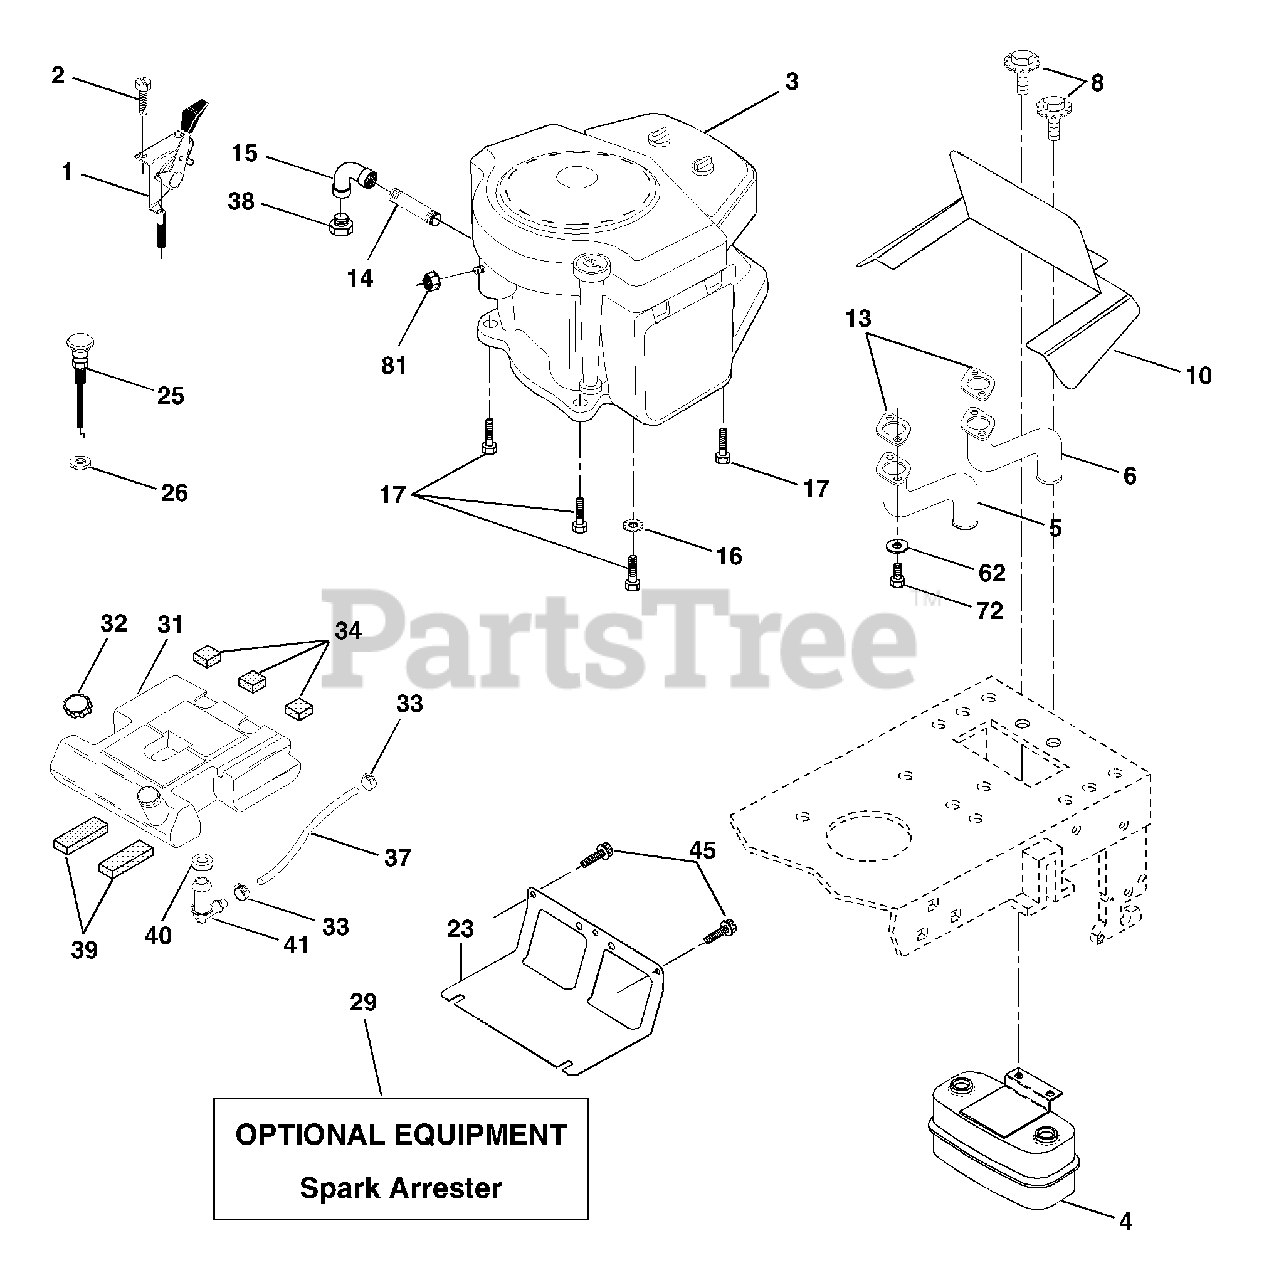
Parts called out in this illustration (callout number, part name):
1	Control Th/Flag 180 LH 36"
2	Screw Hex Thd Cut 1/4-20x5/8 T
4	Muffler Asm Twin Lo-Tone
5	Pipe Exhaust LH Intek
6	Pipe Exhaust RH Intek
8	Bolt 5/16-18 UNC x 3/4 w/Sems
10	Shield Browning Intek II
13	Muffler Gasket
14	Nipple Pipe 3/8 Npt X 4-1/2"
15	Elbow Std 90 Degree 3/8-18 Npt
16	Washer Lock Ext Tooth 3/8
17	Screw Thdrol 3/8-16 x 1-1/2
23	Shield Heat
25	Choke Control 37"
26	Nut, Keps 3/8-24 UNF
29	Kit Spark Arrestor (Flat Scrn)
31	Tank Fuel 3 50 Rear YTGT
32	Cap Asm Fuel W/sym Vented
33	Clamp Hose Black
34	Pad, Spacer
37	Line Fuel
38	Plug Oil Drain
39	Pad, Idler
40	Bushing
41	Stem Tank Fuel
45	Screw Hexwsh Thdr 3/8-16 x 3/4
62	Washer Lock 5/16
72	Screw Hex Hd Cap 5/16-18 x 3/4
81	Nut Keps Hex 1/4-20 UNC
